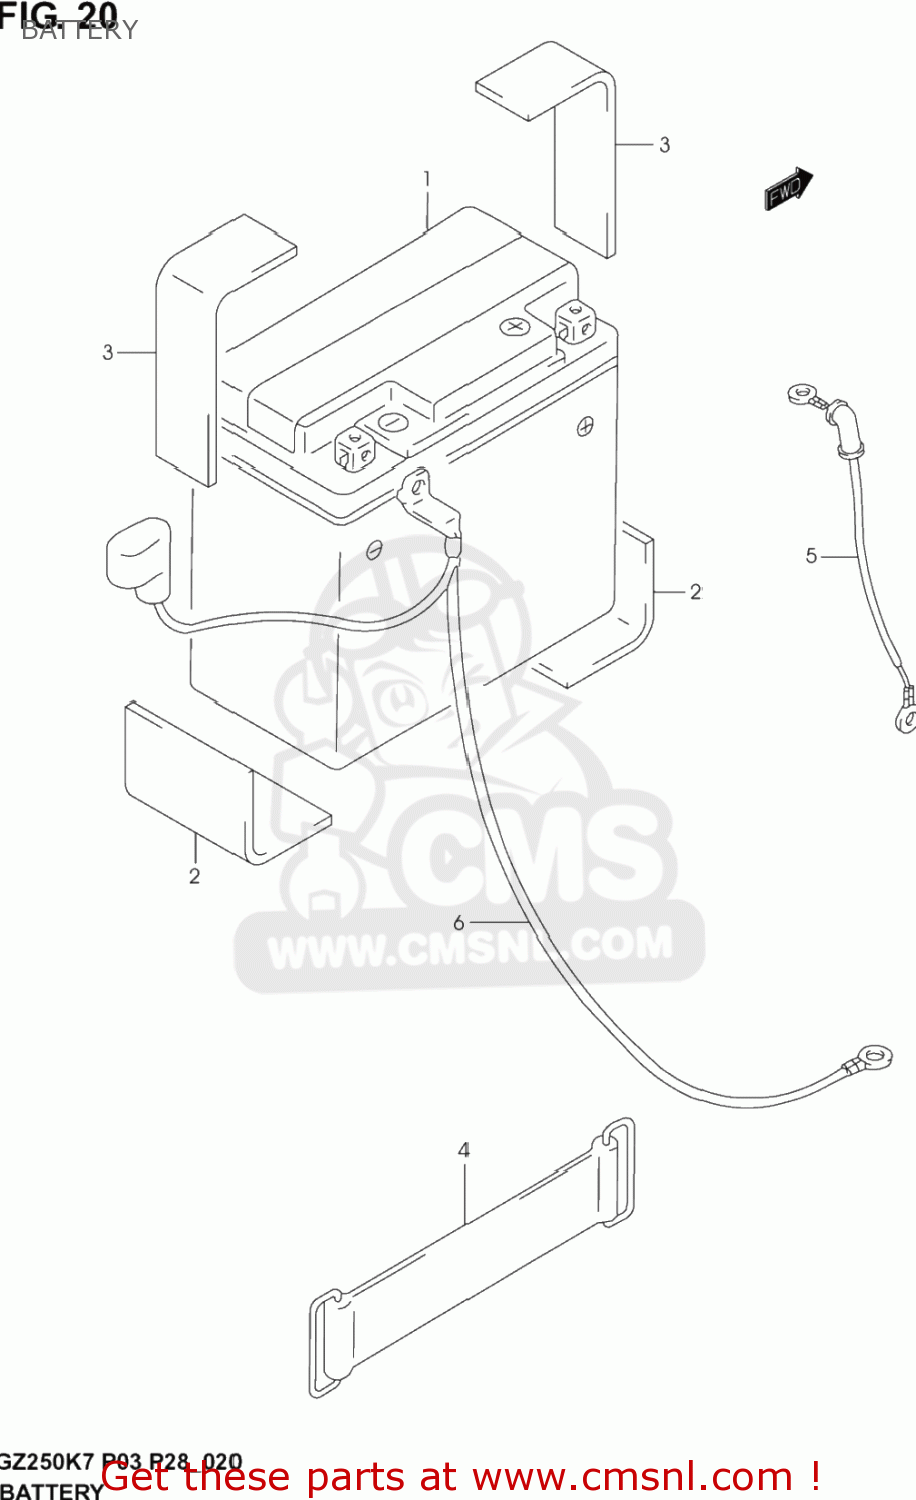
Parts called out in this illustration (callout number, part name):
1	BATTERY ASSY (FTX7L-BS, 12V6A
2	PROTECTOR,BATTERY
3	PROTECTOR (20X90X3)
4	BAND
5	WIRE, BATTERY (+)
6	WIRE,BATTERY MINUS
